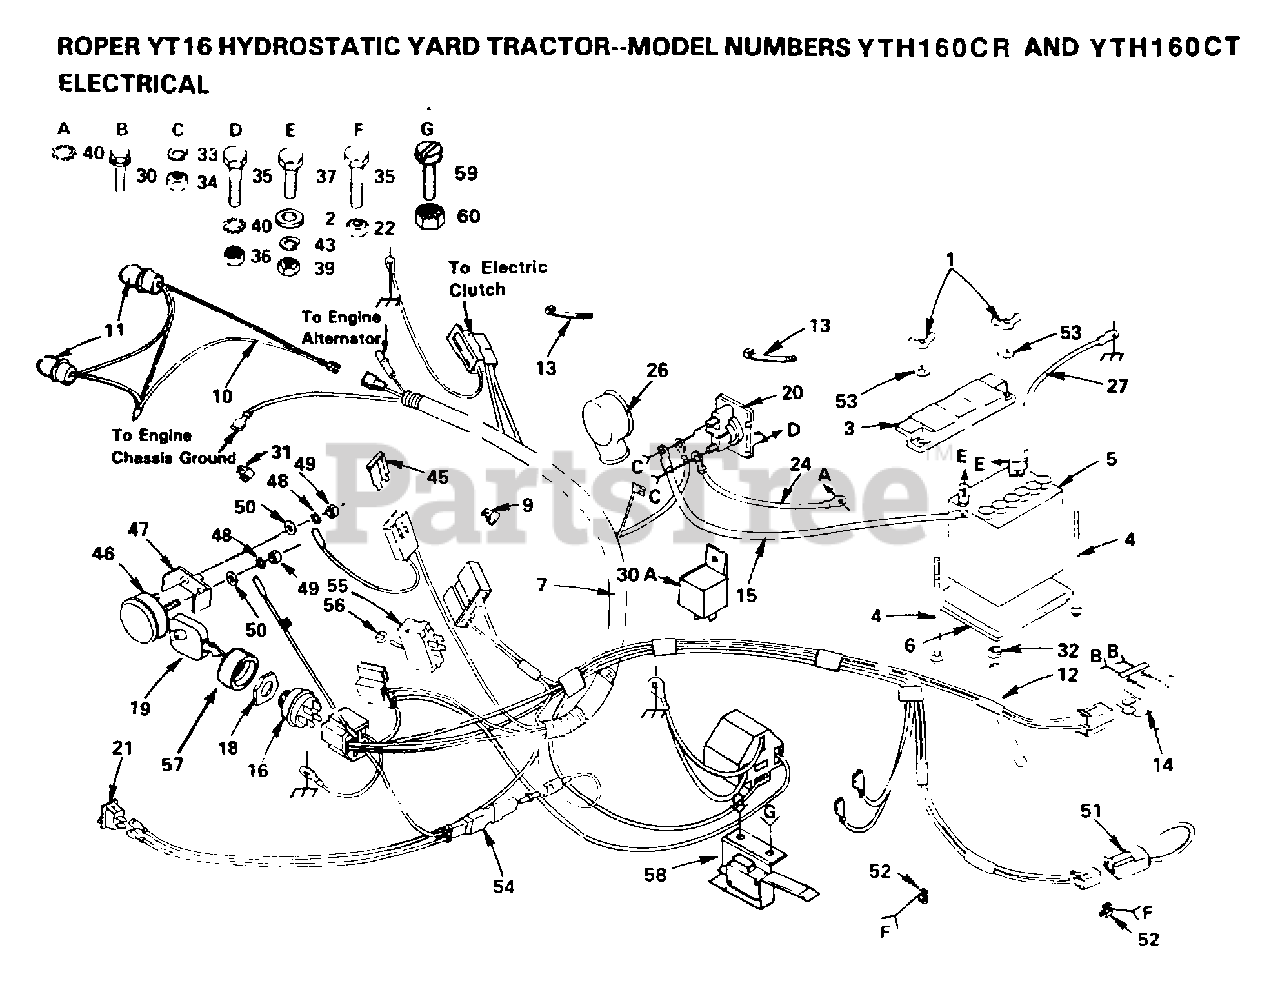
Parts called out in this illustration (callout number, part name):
2	WASHER
4	BOLT
6	"TRAY T, BATTERY"
10	HARNESS T
13	WIRE TIE
14	SWITCH-INTER. GT
15	CABLE-BATTERY T
21	SWITCH LT
27	CABLE T
30	SCREW
30A	RELAY ASSY T
31	CLIP T
32	HOSE CLAMP T
34	NUT
35	BOLT
36	NUT
37	BOLT LT
43	LOCKWASHER
45	FUSE HYT
46	AMMETER T
50	WASHER
52	CLIPT
53	LOCKWASHER GT
55	SWITCH.PTO.T
56	HEX NUT T
60	"NUT,KEPS"
